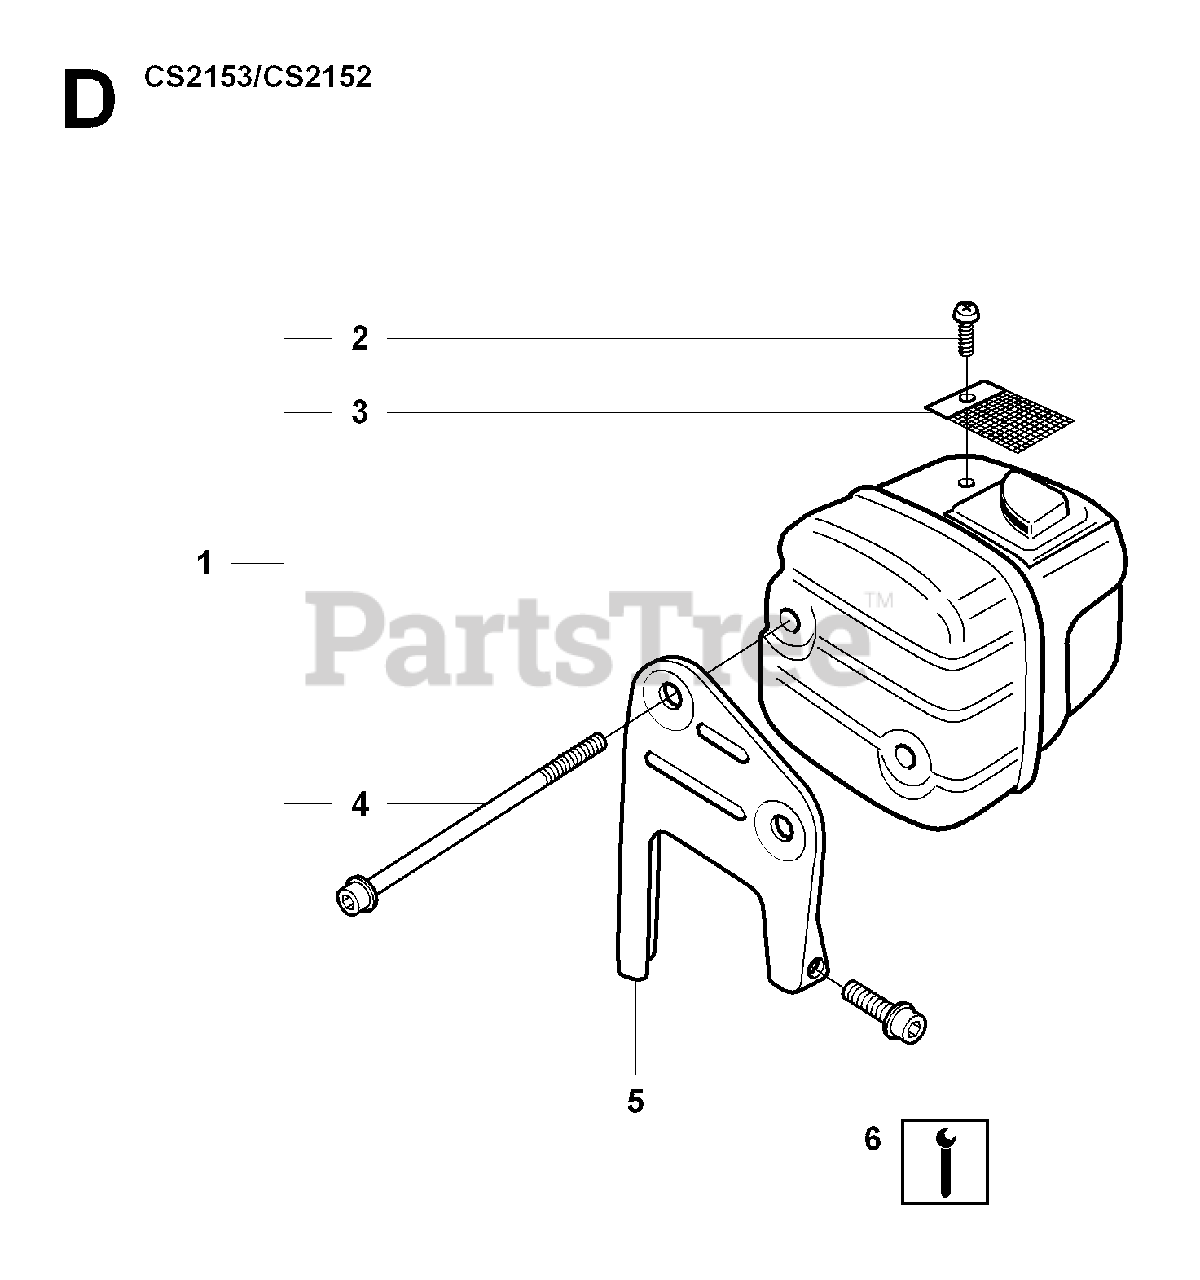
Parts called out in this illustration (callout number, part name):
1	MUFFLER
3	RP SCREEN
5	SUPPORT
